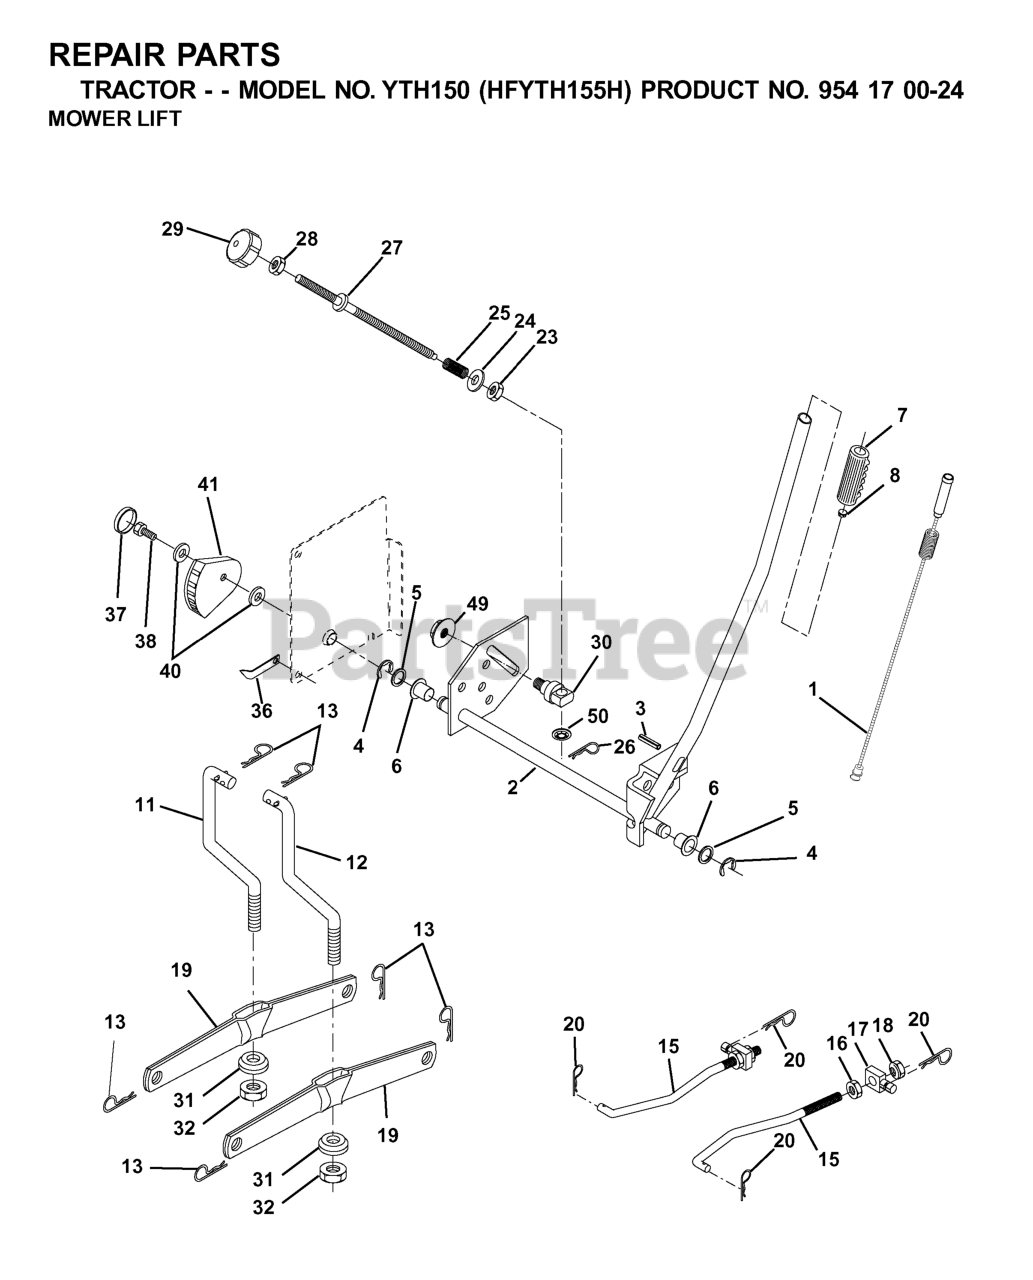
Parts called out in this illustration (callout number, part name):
1	WIRE ASM INNER W/ PLUNGER LT
2	SHAFT ASM R HANDLE
3	PIN GROOVE.
4	RETAINING RING LT
6	BEARING.NYLON
7	GRIP HANDLE
8	PLUNGER BUT KIT
11	LINK LIFT LH
12	LINK LIFT RH
13	RETAINER-SPRNG RB
15	LINK.SUSPENSION.FRONT
16	NUT.HEX.JAM.1/2-13
17	TRUNION
18	NUT.LK.W/WSH.1/2.
19	ARM.REAR.SUSPENSION
20	SPRING RETAINER
25	SPRING**
26	RETAINER CLIP
27	ROD ADJ LIFT
28	NUT
29	KNOB INF 3/8-16
31	BEARING.PIVOT.LIFT
32	NUT CROWNLOCK 3/8-24
36	POINTER, HEIGHT INDICATOR(2 2)
38	SCREW 5/16-18X1
41	IND. HEIGHT STLT
49	NUT
50	NUT PUSH M
